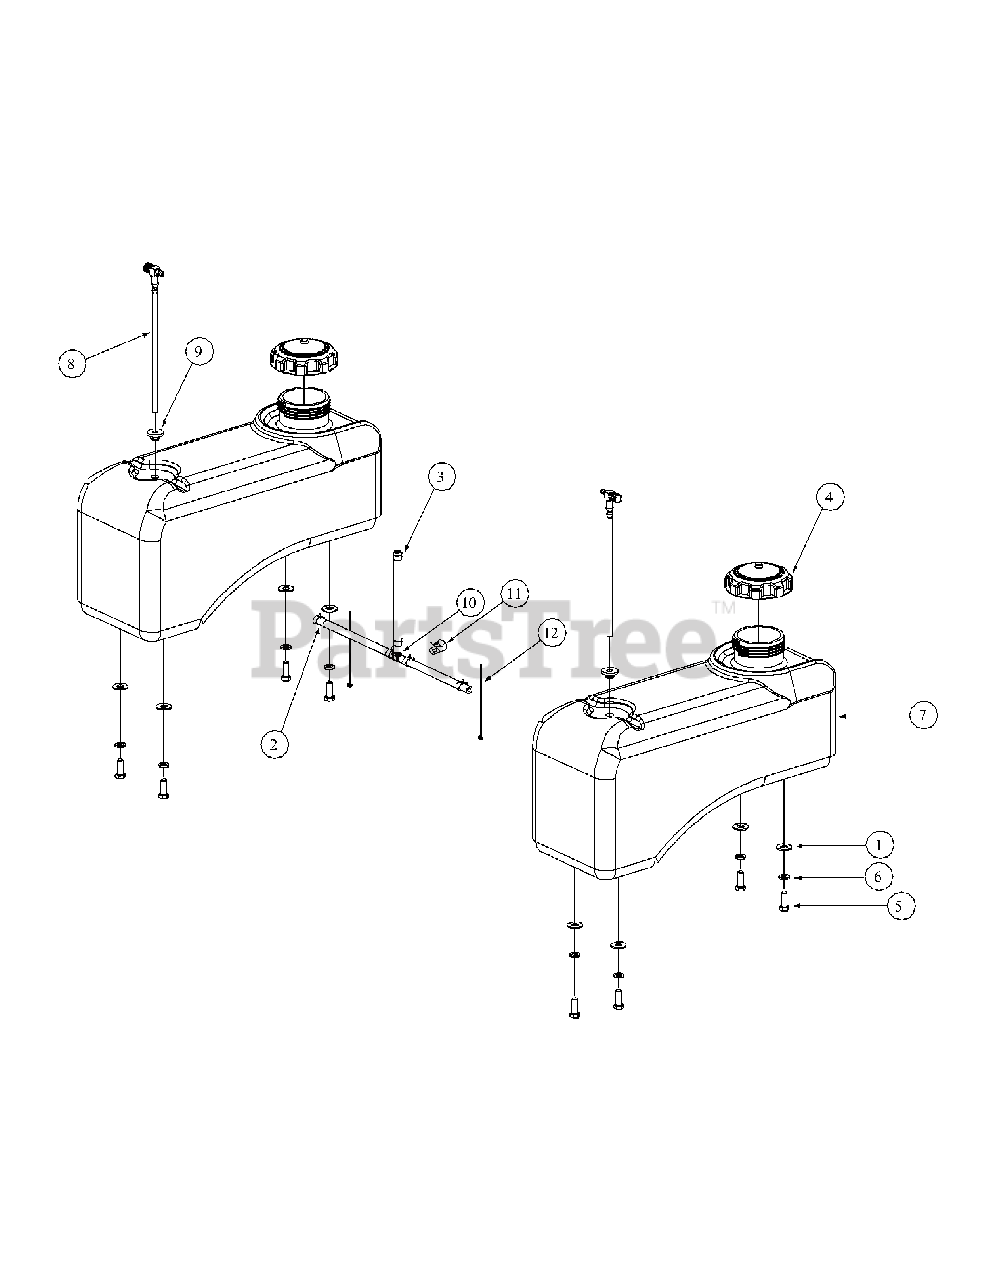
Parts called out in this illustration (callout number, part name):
1	Flat Washer, .406 ID, 1.0 OD, .105
2	Hose, 1/4" Fuel Line (in inches)
3	Clamp, Union
4	Fuel Cap, 3.5
5	Hex, Cap Screw, 3/8-16, .88
6	Lock Washer, 3/8
7	Fuel Tank
8	Fuel Fitting
9	Bushing, Fuel Tank
10	Tee Fitting, Fuel
11	Clamp
12	Cable Tie
